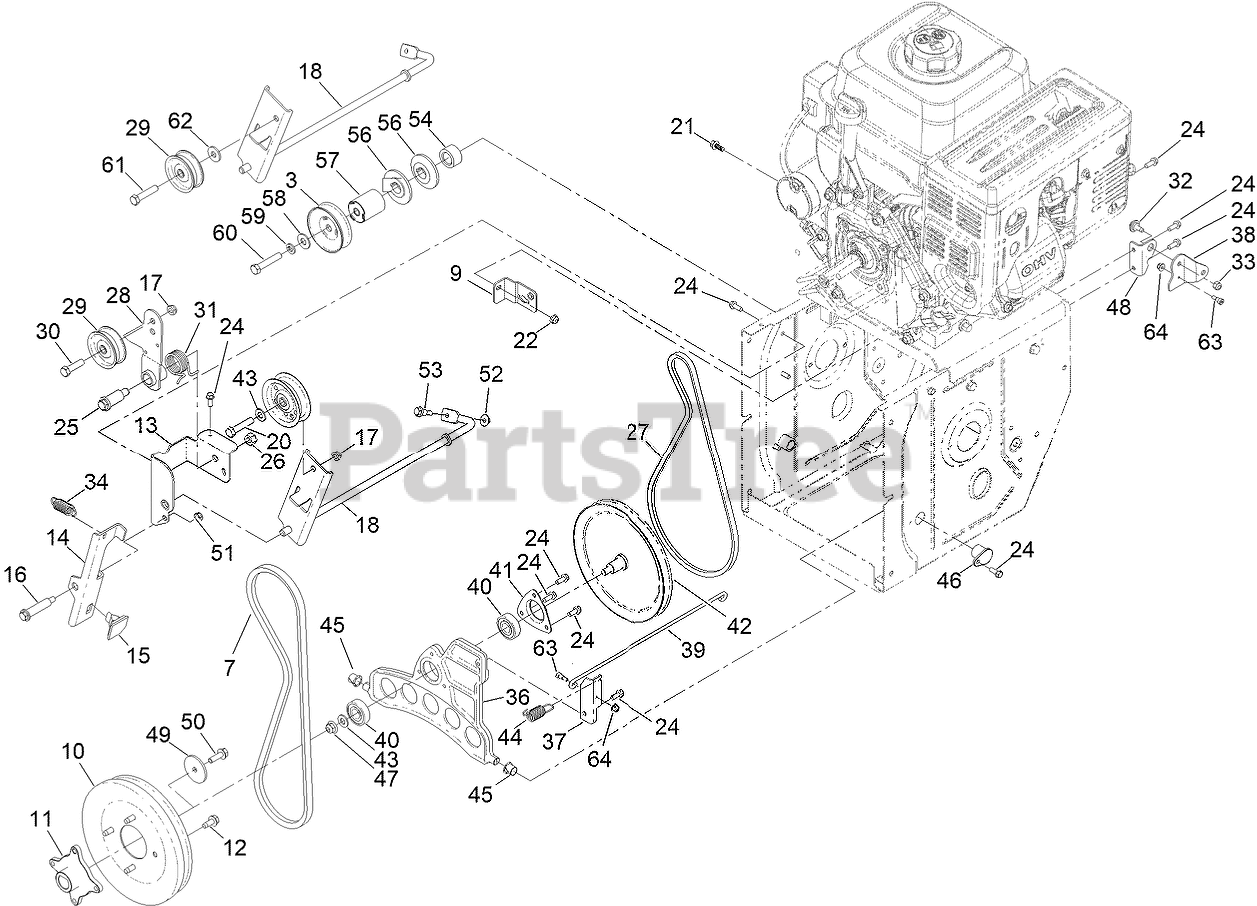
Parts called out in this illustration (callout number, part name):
3	PULLEY-IMPELLER
7	BELT-V
9	BRACKET-CLUTCH, IMPELLER
10	PULLEY-IMPELLER
11	HUB-PULLEY
12	SCREW-HWHTF
13	BRACKET-BRAKE, CLUTCH
14	BRAKE ARM
15	PAD-BRAKE
16	BOLT-SHOULDER
17	NUT-HEX
18	ARM-CLUTCH, IMPELLER
20	SCREW-HH
21	SCREW-HHF
22	NUT-HF
24	SCREW-HWH
25	BOLT-SHOULDER
26	NUT-HEX
27	BELT,3L P21 DRIVE
28	ARM-IDLER, TRACTION
29	PULLEY-IDLER
30	SCREW-HH
31	SPRING-TORSION
32	SCREW-SHOULDER
33	NUT-HEX
34	SPRING-EXTENSION
36	PLATE-FRICTION, WHEEL
37	BKT-TRACTION PLATE
38	BELLCRANK-DRIVE
39	LINK-TRACTION, HD
40	BEARING-BALL
41	RETAINER-BEARING
42	PULLEY-TRACTION
43	WASHER-FLAT
44	SPRING-EXTENSION
45	BUSHING-NYLINER
46	BUSHING-PLATE, TRACTION
47	NUT-HF, NI
49	WASHER-PLAIN
50	SCREW-HHF
51	NUT-HEX
52	NUT-HF
53	BOLT-SHOULDER
54	SPACER
56	SHEAVE-TRACTION
57	SPACER-PULLEY
58	WASHER-PLAIN
59	WASHER-LOCK
60	SCREW-HH
61	SCREW-HH
62	WASHER-HARDENED
63	SCREW-SHOULDER
64	NUT-HF
